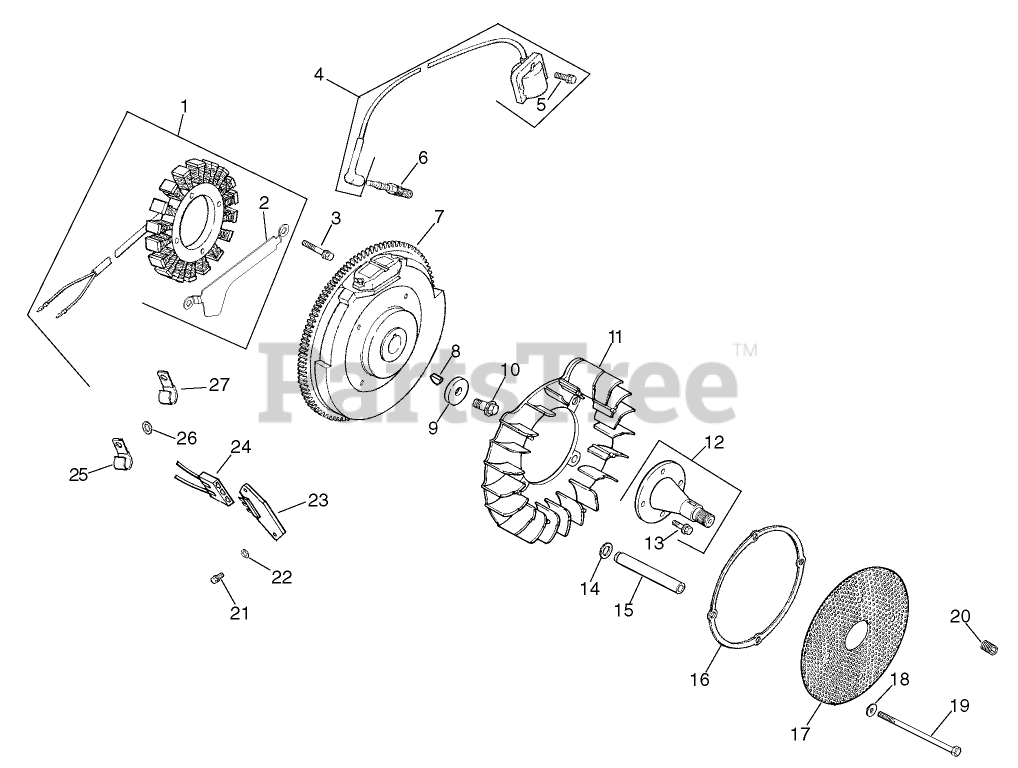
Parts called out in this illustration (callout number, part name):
1	Kit, 15 amp stator (Includes 2)
2	Bracket-Wire, Stator
3	SCREW-THREAD FORMING (M5X0.8X25)
4	Kit, ignition module (Includes 5)
5	Screw-Socket, Hex (M5x0.8x25)
6	Spark Plug
7	Flywheel
8	KEY (3/16 X 5/8)
9	WASHER-FLAT (13/32)
10	SCREW-FLANGE (M10X1.5X45)
11	Fan
12	Kit, front drive shaft (Includes 13)
13	Screw-HF (M8x1.25x25)
14	Washer-Spring (10MM)
15	Spacer
16	Ring-Support
17	Screen-Grass
18	WASHER-FLAT (1/4)
19	Screw-HH (M6x1.0x100)
20	Screw-Set (10-24X.25)
21	SCREW-PHL HD (11-16X.88)
22	WASHER-FLAT (.188)
23	Rectifier-Regulator, 15 amp
24	Connector (3 contact)
25	CLIP-CABLE
26	WASHER-FLAT (1/4)
27	Clip-Cable
